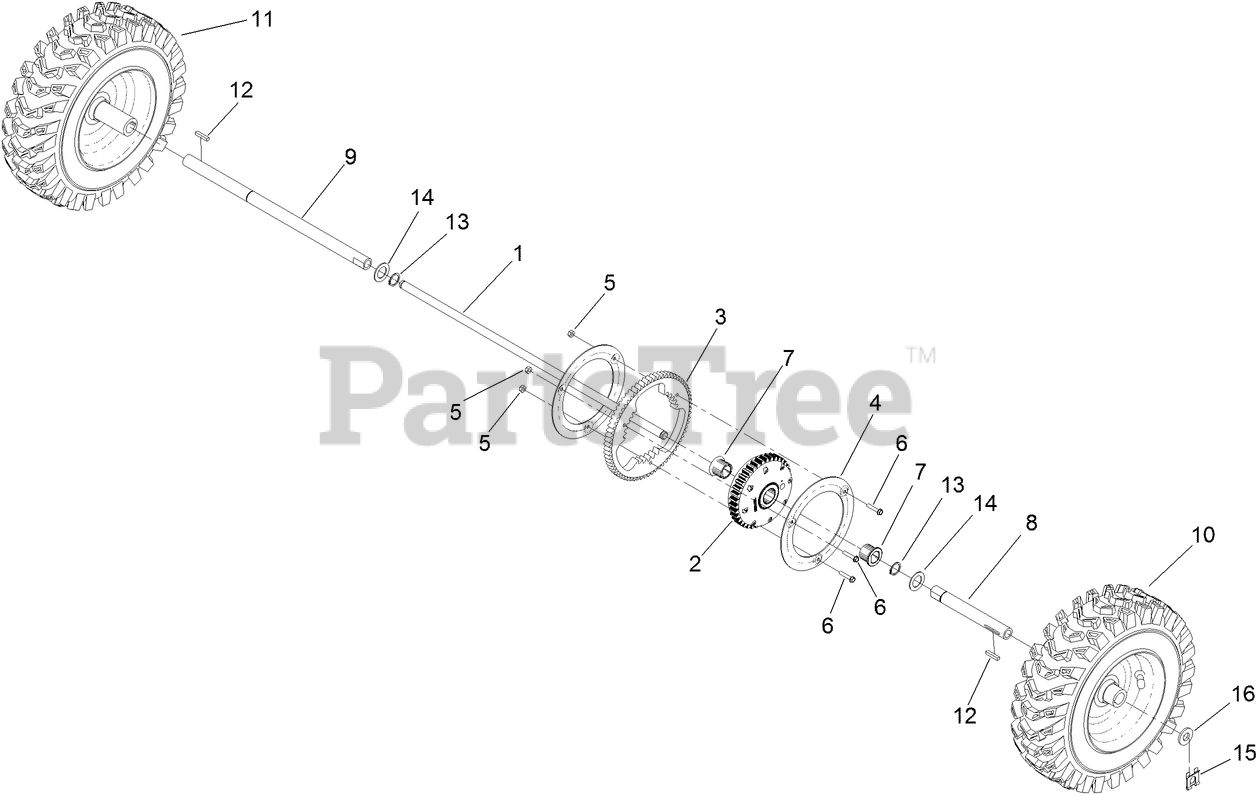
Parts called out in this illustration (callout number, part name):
2	TRANSMISSION
3	GEAR-AXLE
4	PLATE-GEAR
5	NUT-LOCK, NI
6	SCREW-HWH
7	GEAR-TUBE, AXLE
8	TUBE-AXLE
9	TUBE-AXLE
10	LH WHEEL AND TIRE ASM
11	RH WHEEL AND TIRE ASM
12	KEY-SQUARE
13	Ring-Snap
14	WASHER-THRUST
15	CLIP-PIN
16	WASHER-THRUST, PLAIN
